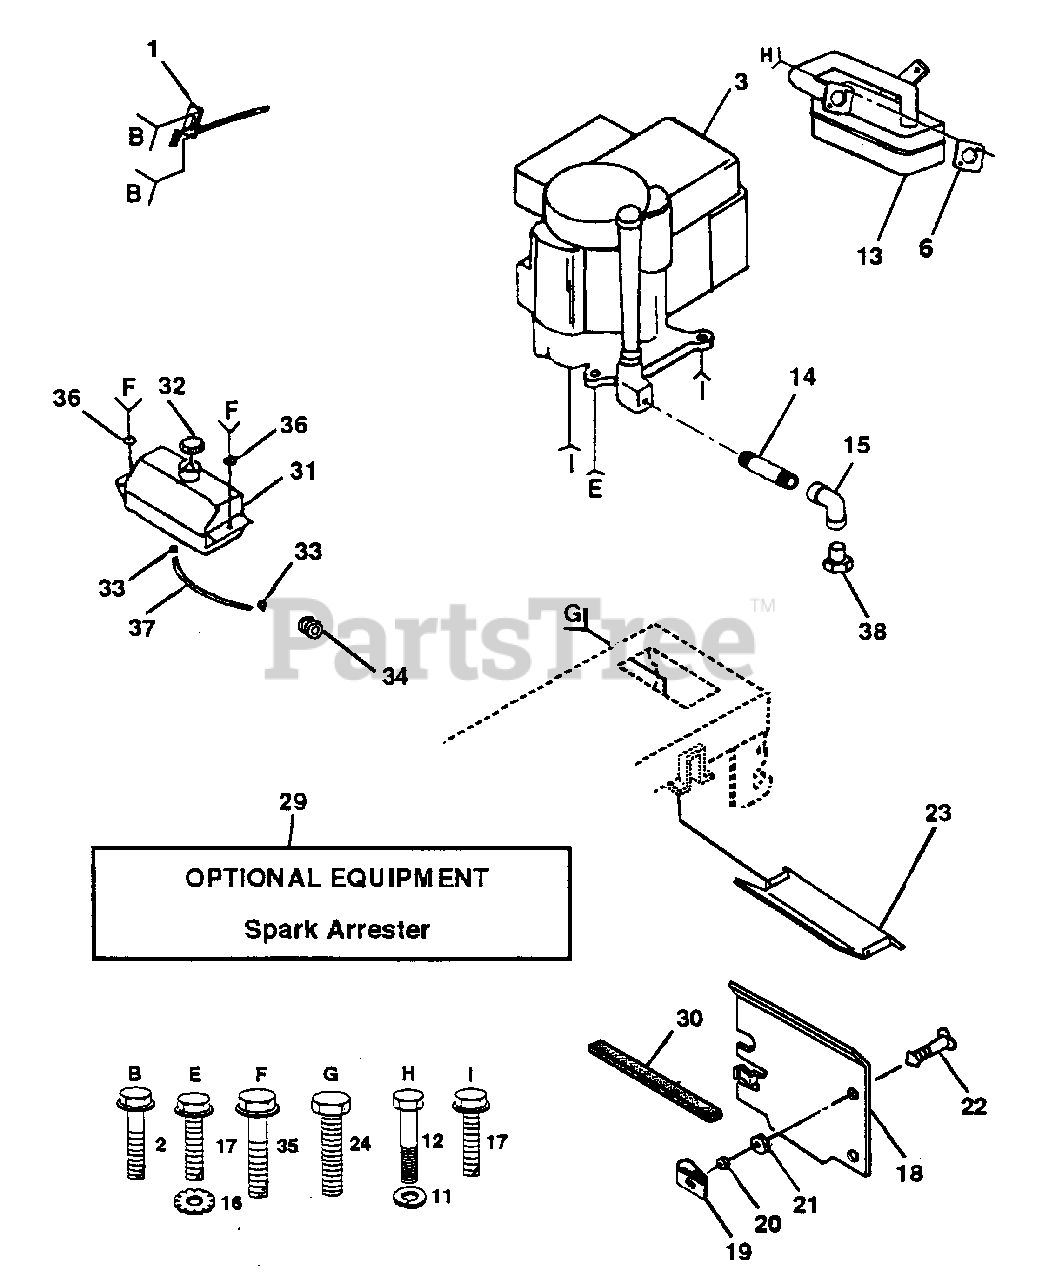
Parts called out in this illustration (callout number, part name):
1	Control Th/ch RH Blk Tee Eec (AYP part number)
2	Screw Hex Thd Cut 1/4-20x5/8 T (AYP part number)
6	Gasket Eng 1 313 Id Tin Plated (AYP part number)
11	Washer Lock Hvy Hlcl Spr 5/16 (AYP part number)
12	Screw Hexhd Cap 5/16-18x3/4 (AYP part number)
13	Muffler LT B&s 12/12.5 HP (AYP part number)
14	Nipple Pipe 3/8 Npt X 3" (AYP part number)
15	Elbow Std 90 Degree 3/8-18 Npt (AYP part number)
16	Washer Lock Ext Tooth 3/8 (AYP part number)
17	Screw Thdrol 3/8-16x1-1/4 TYTT (AYP part number)
18	Shield Heat LT (AYP part number)
19	Receptacle 1/4 Turn dacrotized (AYP part number)
20	Retainer 1/4 Turn 365 OD x .222 ID (AYP part number)
21	Washer 9/32 x 5/8 x 16 Ga (AYP part number)
22	Stud 1/4 Turn (replaces 105751)
23	Shield Heat Browning LT/YT (AYP part number)
24	Screw Tap Hex #10-24unc X 1/2 (AYP part number)
29	Kit Spark Arrestor 1 25
30	Pinch Weld Hood Black 2.00
31	Tank Fuel Front 2.00 (AYP part number)
32	Cap Asm Fuel W/sym Vented (AYP part number)
33	Clamp Hose Blk (AYP part number)
34	Bushing Snap Nyl Blk Fuel Line (AYP part number)
35	Screw Hexwsh Thdrol 1/4-20x3/4 (AYP part number)
36	Washer 9/32 X 7/8 X 16ga (AYP part number)
37	Line Fuel 9 20" (AYP part number)
